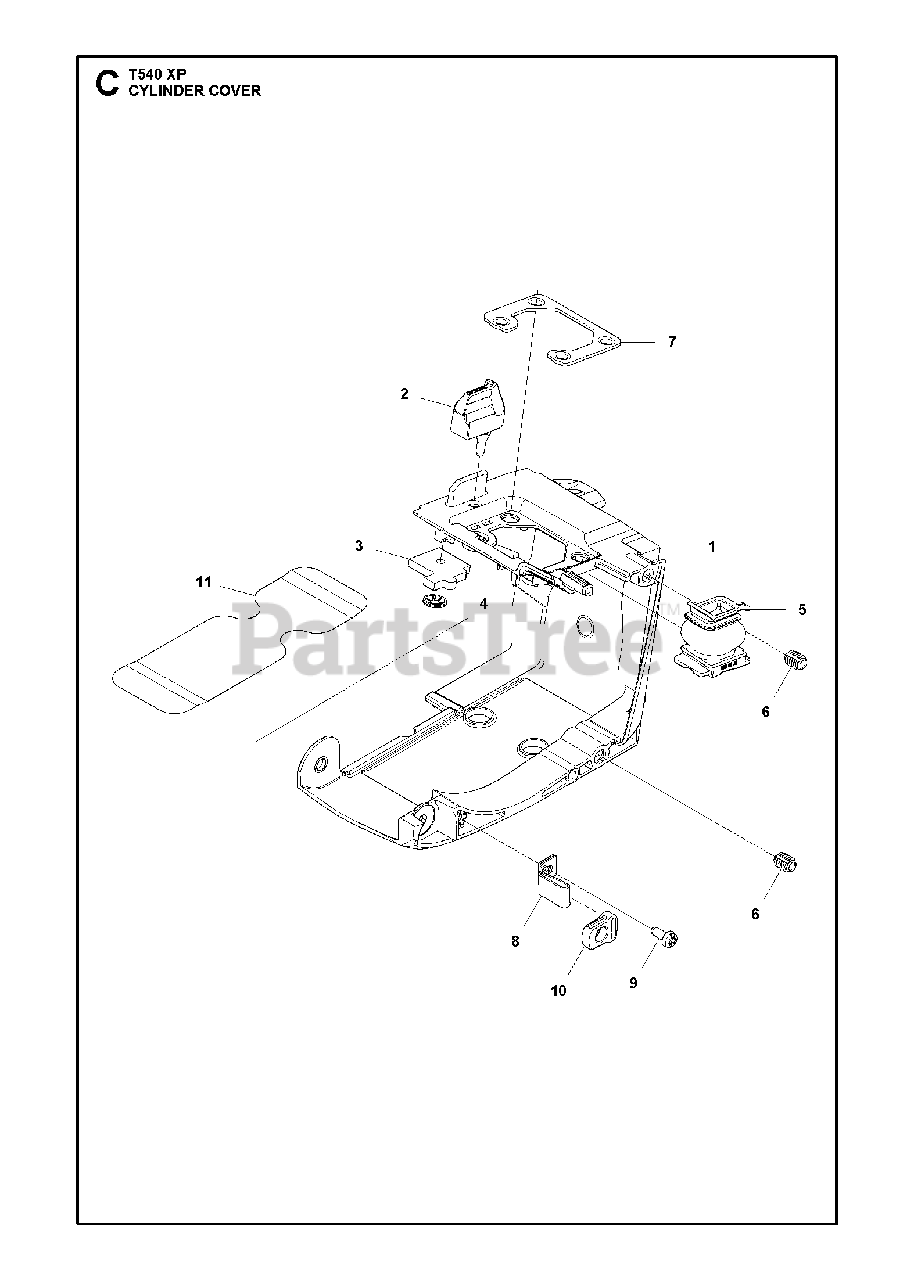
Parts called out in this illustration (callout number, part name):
1	CYLINDER COVER ASSY
4	LOCK WASHER
6	THREAD INSERT
7	PLATE CYLINDER COVER
8	STRAP ANTIVIBRATION FRONT HAND
9	SCREW CITXPANT
10	WEDGE DEFLECTION LIMITER
11	HEAT DEFLECTOR
